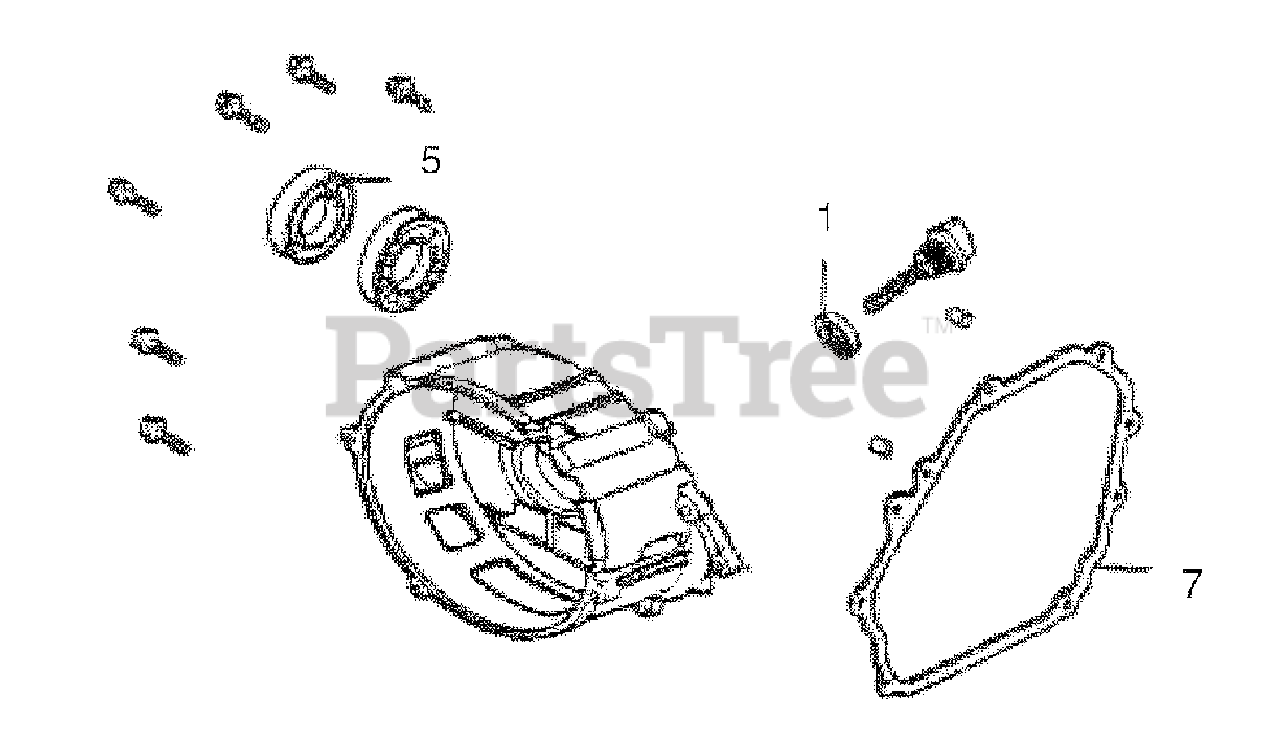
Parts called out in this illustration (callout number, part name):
1	CAP ASS, OIL FILLER
5	OIL SEAL 25X41.25X6
7	GASKET, CASE COVER
